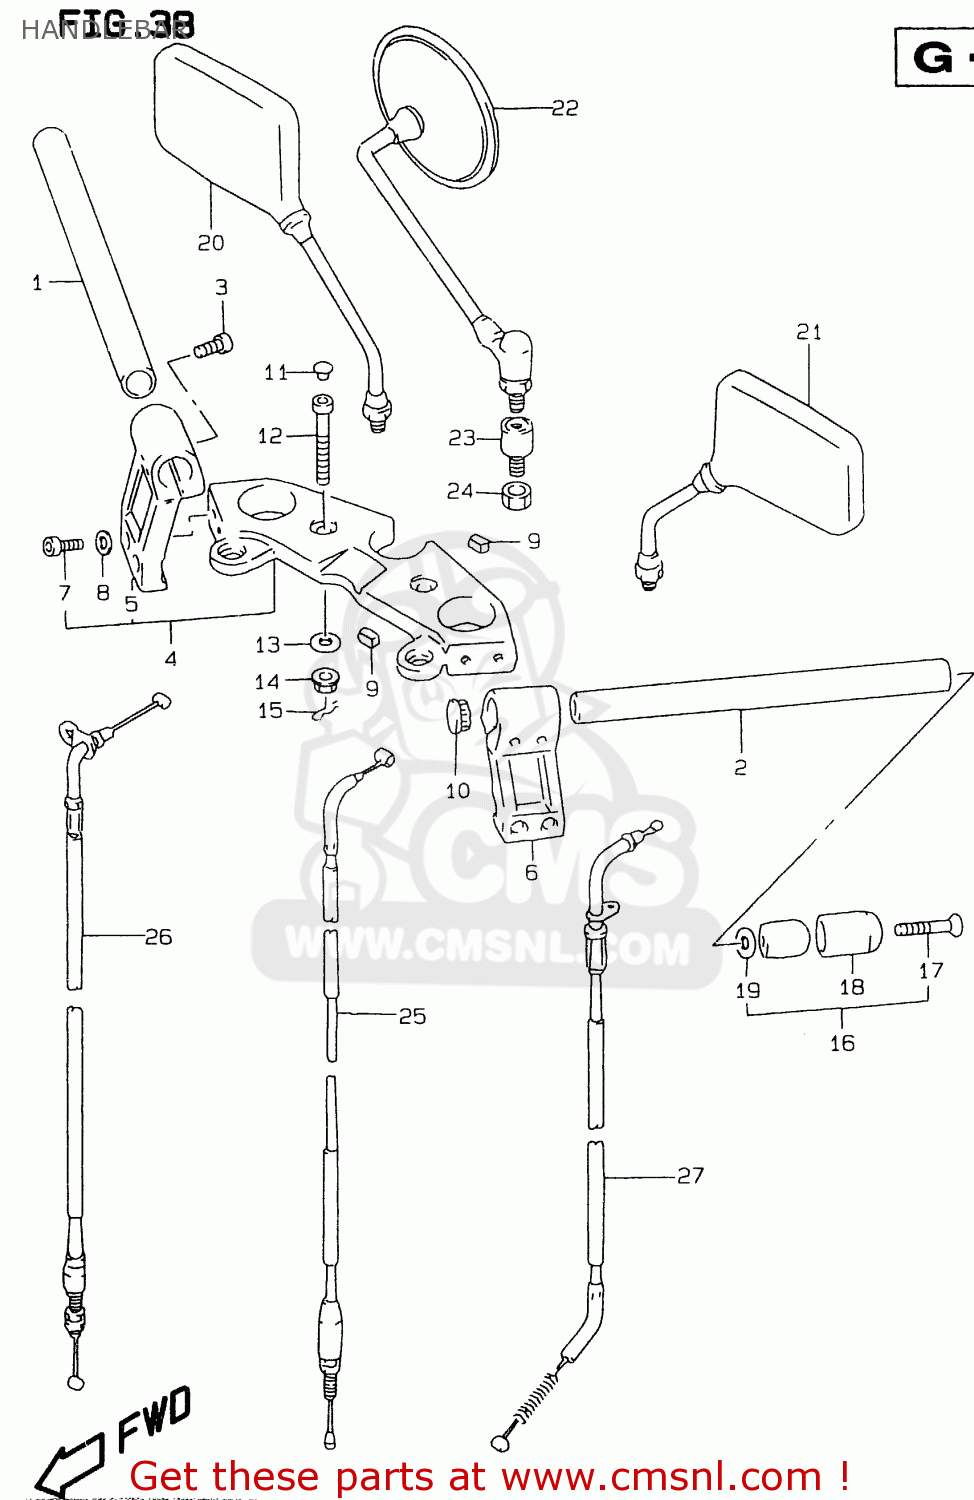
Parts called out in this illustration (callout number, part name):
1	HANDLEBAR,R
2	HANDLEBAR,L
3	BOLT,CL.COVER
4	HOLDER ASSY,HANDLEBAR
5	HOLDER,HANDLEBAR,R(SILVER)
6	HOLDER,HANDLEBAR,L(SILVER)
7	BOLT
8	WASHER
9	CUSHION,HANDLE HOLDER
10	CAP,HANDLEBAR
11	CAP(OD:11)
12	BOLT(10X66)
13	WASHER(10.5X30X3.2)
14	NUT
15	PIN 20X20
16	BALANCER SET,HANDLEBAR
17	SCREW
18	CAP,HANDLE BALANCER
19	SPACER,BALANCER
20	MIRROR ASSY,RE
21	MIRROR ASSY,LH
22	MIRROR ASSY,RH
23	CUSHION,REAR VIEW MIRROR
24	NUT
25	CABLE ASSY,CLUTCH
26	CABLE ASSY,THROTTLE
27	CABLE,STARTER
